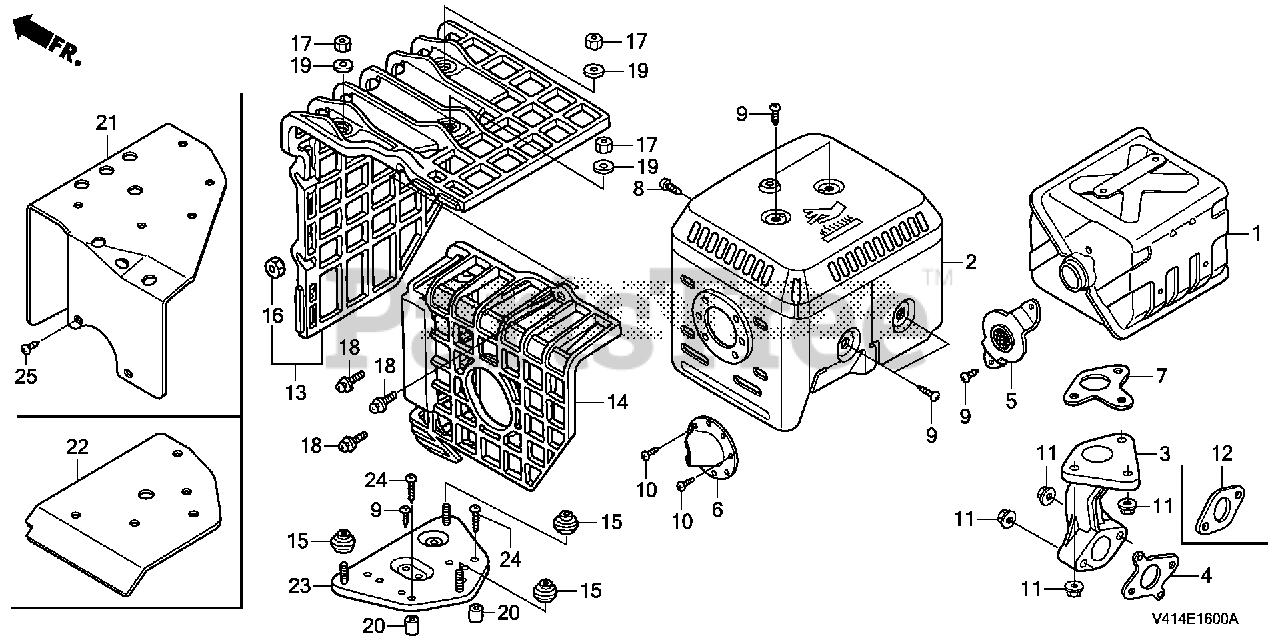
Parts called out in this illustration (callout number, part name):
1	MUFFLER
2	PROTECTOR, MUFFLER
5	FLANGE, BAFFLE
6	CAP, MUFFLER
7	GASKET, MUFFLER (NIPPON LEAKLESS)
7	GASKET, MUFFLER (THAI LEAKLESS)
8	SCREW, TAPPING (6X10)
9	SCREW, TAPPING (5X8)
10	SCREW, TAPPING (4X6) (TO INSTALL OPTIONAL SPARK ARRESTER)
11	NUT, FLANGE (8MM)
12	GASKET, EX. PIPE
13	COVER, MUFFLER PROTECTOR
14	COVER, RR. MUFFLER
15	SPACER, MUFFLER COVER
16	NUT, U (6MM)
17	NUT, HEX. (5MM)
18	SCREW-WASHER (6X20)
19	WASHER, PLAIN (5MM)
20	COLLAR, AIR CLEANER HOUSING
22	PROTECTOR, MUFFLER (UPPER)
23	BASE COMP
24	SCREW, TAPPING (5X25)
